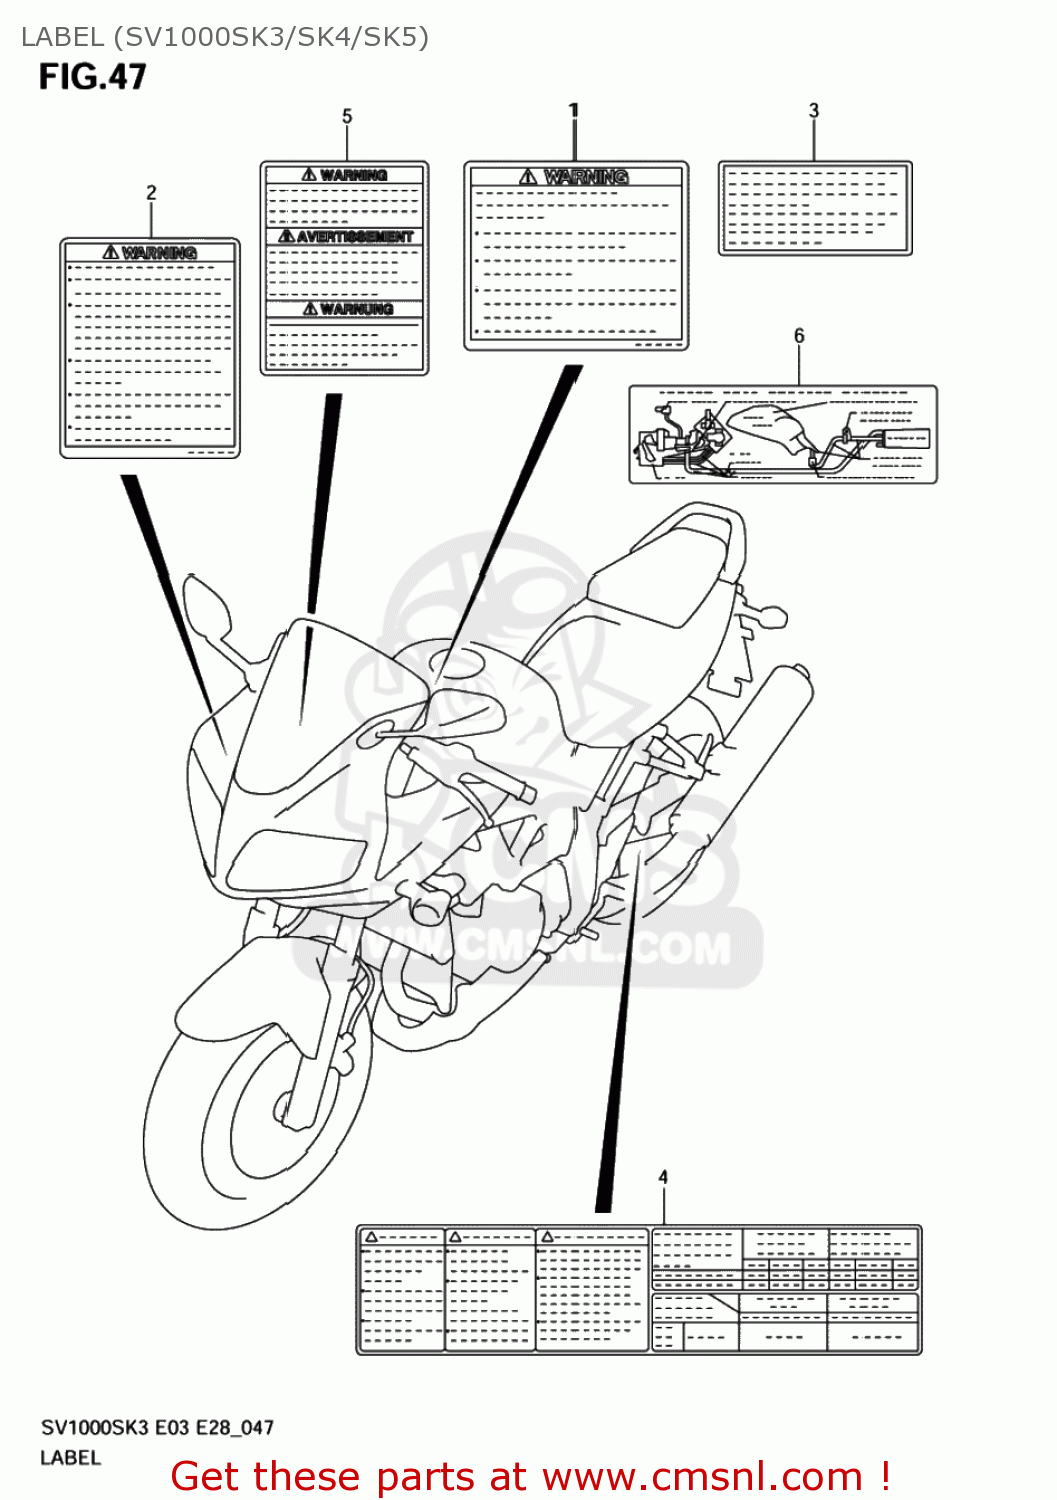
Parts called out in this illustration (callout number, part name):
1	LABEL,GENERAL WARNING
2	LABEL,SCREEN
3	LABEL,MANUAL NOTICE
4	LABEL,TIRE INFORMATION
5	LABEL,WARNING STEERING
6	LABEL,VACUUM HOSE ROUTING
7	MANUAL,OWNER'S
